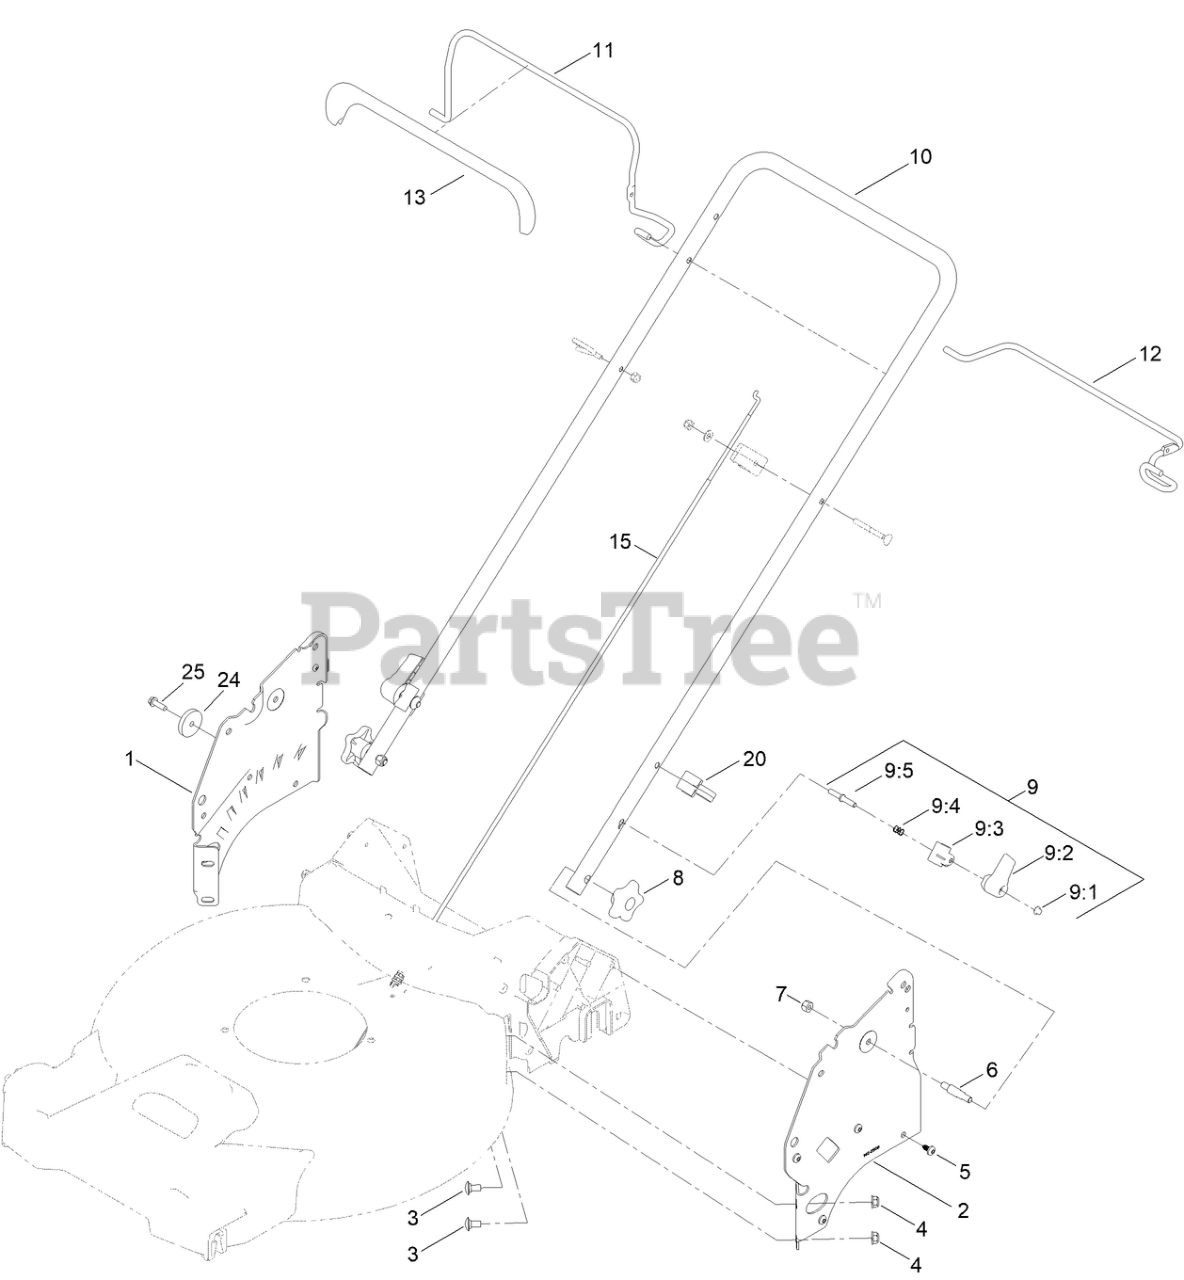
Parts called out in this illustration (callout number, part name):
1	PLATE-HANDLE, RH
2	PLATE-HANDLE, LH
3	SCREW-CARR
4	NUT-FLANGE, NI
5	SCREW-PLASTIC,PH
6	BOLT-SHOULDER, HANDLE
7	NUT-LOCK, NI
8	KNOB-HANDLE
9	QUICK RELEASE ASM
9:1	NUT-PUSH
9:2	LEVER-RELEASE
9:3	ANCHOR-SPRING
9:4	SPRING-COMPRESSION
9:5	ROD-RELEASE
10	HANDLE-UPPER
11	BAIL-BRAKE
12	BAIL-TRACTION
13	COVER-BAIL
15	CABLE-TRACTION
20	GUIDE-CABLE
25	SCREW-HWH
